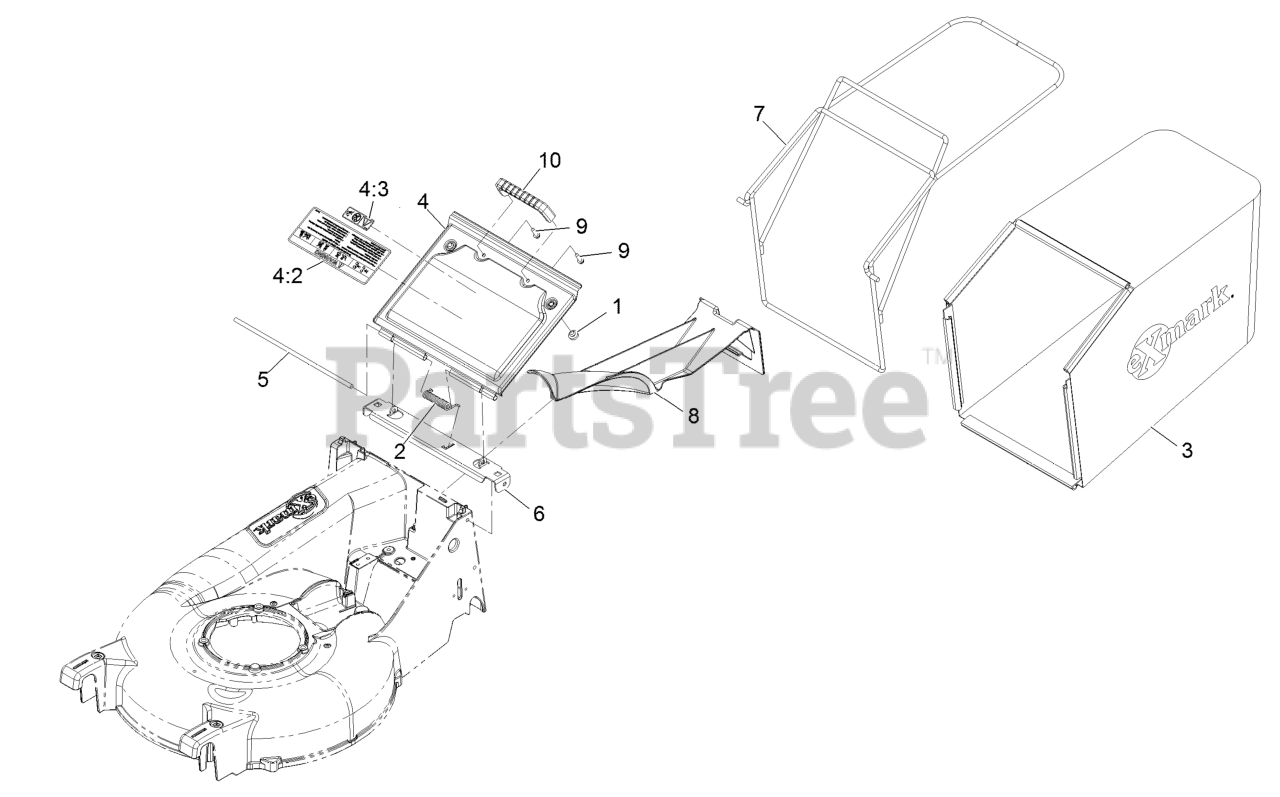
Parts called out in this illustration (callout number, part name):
2	SPRING-TORSION,COVER
3	BAG,GRASS P21
4	DOOR W/DECAL
4:2	DECAL-WARNING DOOR LG
4:3	DECAL-WARNING, BLOCK
5	ROD,DOOR PIVOT
6	BRACKET-DOOR P21
7	WLD,BAG FRAME
8	PLUG,MULCH
9	SCREW-HWH
10	HANDLE-DOOR
